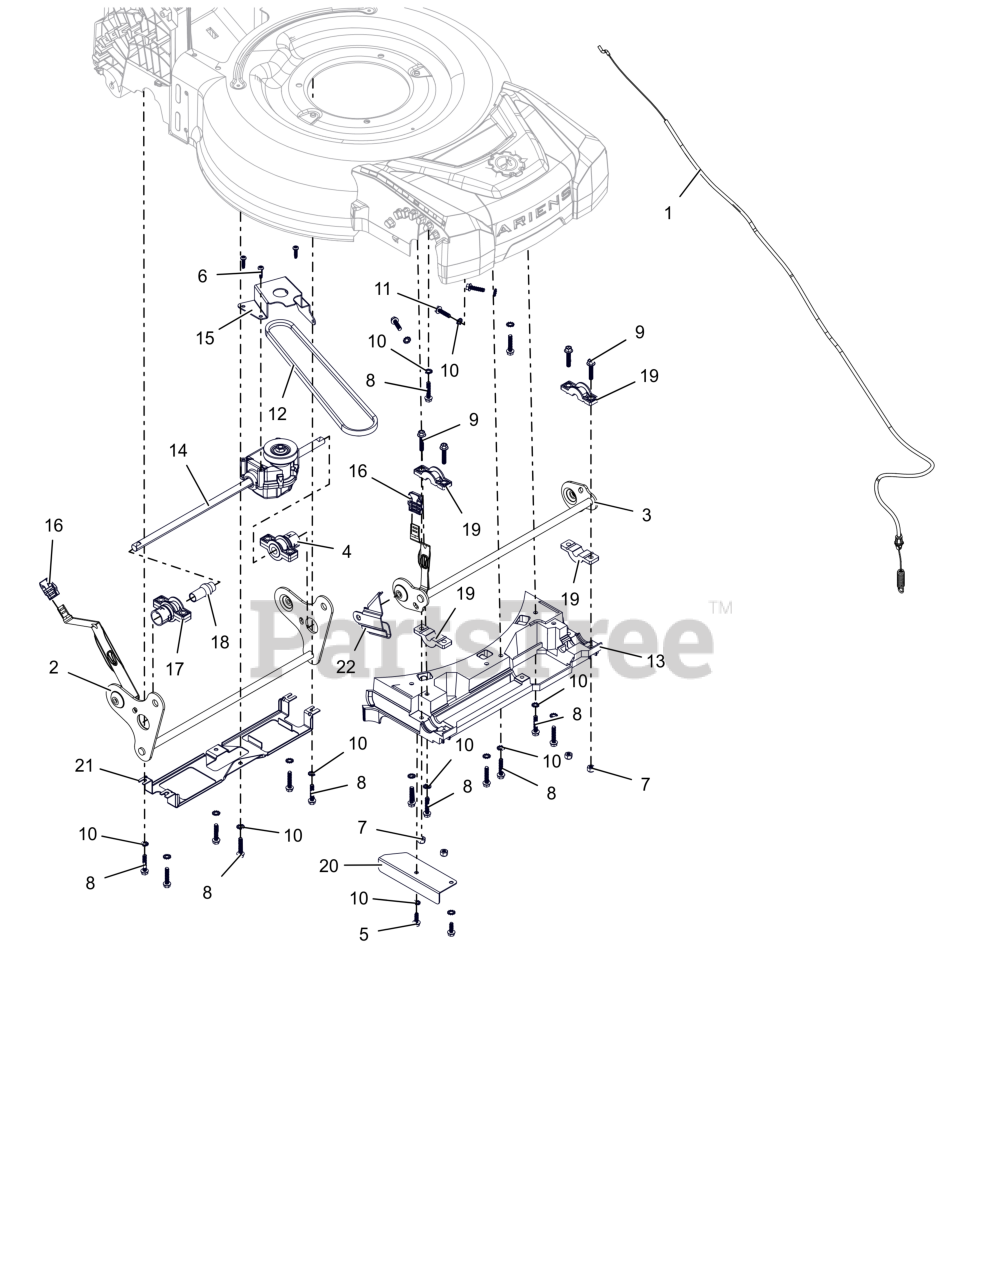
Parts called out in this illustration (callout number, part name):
1	CABLE, RWD TRANSMISSION
2	WLDMT, REAR AXLE - RWD (BLACK)
3	WLDMT, FRONT AXLE - PUSH (BLACK)
4	ASM, BSHG - BRONZE
5	SCR, HI-LO HWH 1/4-15 X .750
6	SCR, TORX TRILOB PH 10-14X.75
7	NUT, NYLOC 1/4-20
8	SCR, HI-LO HWH 1/4-15 X 1.25
9	BLT, HWH 1/4-20 X 1.25
10	WSHR-LK-EXT, .256X.510X.028
11	SCR, HI-LO HWH 1/4-15 X 1.00
12	BELT, RWD
13	TRAY, FRONT
14	ASM, RWD TRANSMISSION - MA 302
15	BRKT, RWD TRANSMISSION (BLACK)
16	GRIP, HOC
17	BUSHING, AXLE - OUTER
18	BUSHING, AXLE - INNER
19	BUSHING, SHAFT - HOC
20	FLANGE, BLOW OUT (BLACK)
21	BRKT, RWD BACK SUPPORT (BLACK)
22	BRKT, ARM SUPPORT (BLACK)
